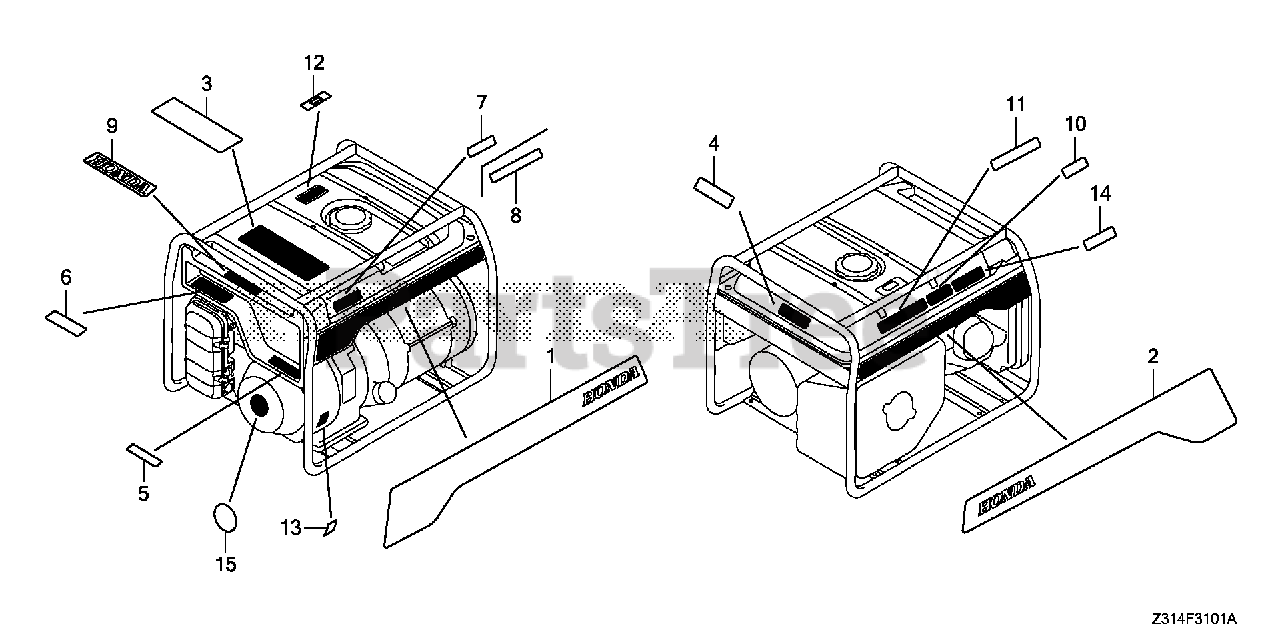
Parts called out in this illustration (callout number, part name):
1	MARK, R. EMBLEM (EG5000CL)
2	MARK, L. EMBLEM (EG5000CL)
3	LABEL, OPERATOR WARNING (E)
4	MARK, SPEC
5	MARK, FR. EMBLEM (EG5000CL)
6	MARK, OPERATION
8	LABEL, OIL ALERT
9	MARK, HONDA
11	LABEL, EX. WARNING
12	PLATE, FUEL INDICATION
13	MARK, OIL CHECK
